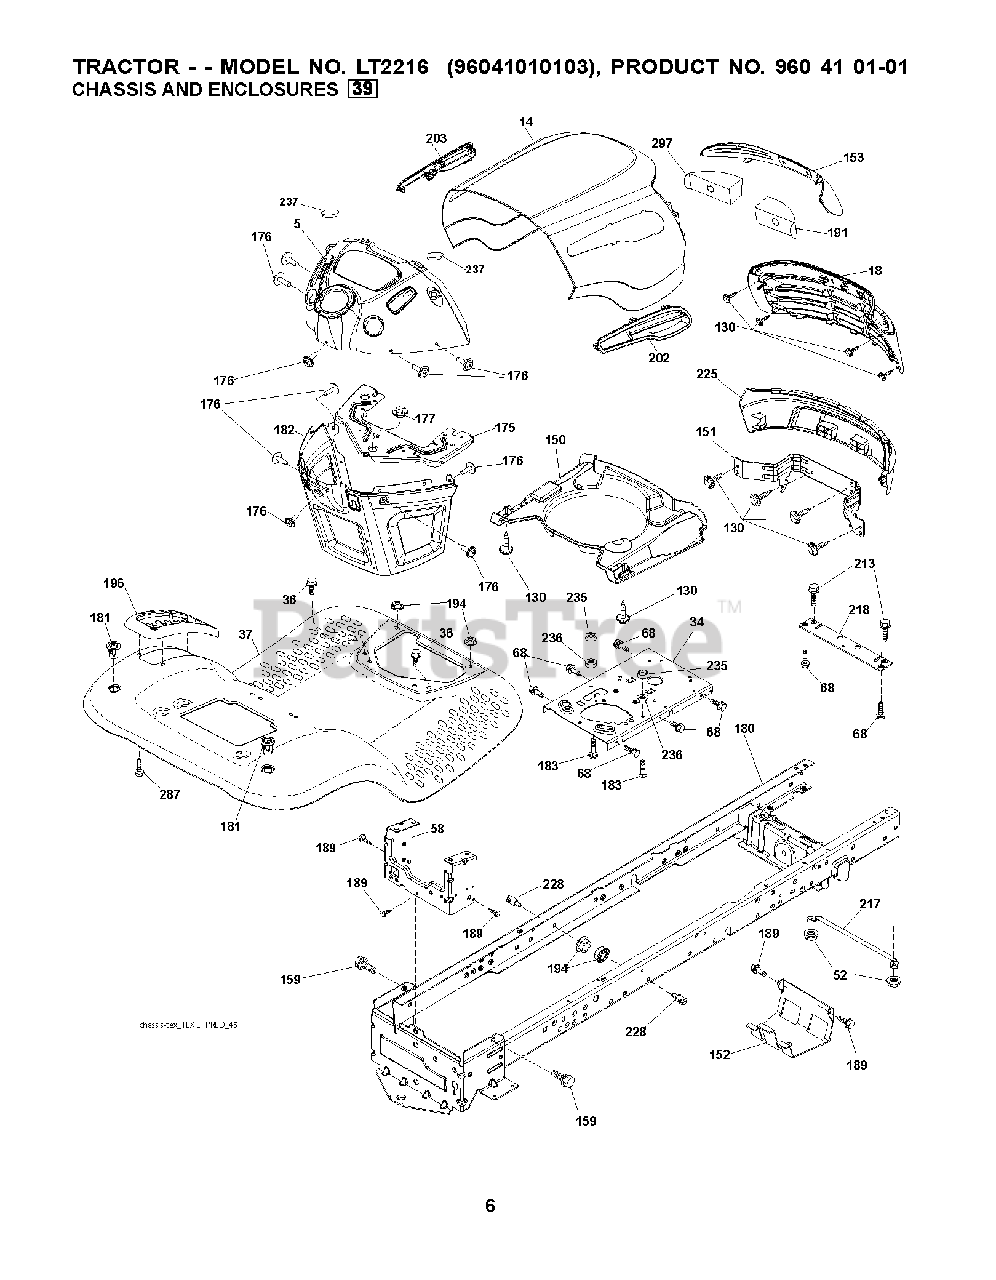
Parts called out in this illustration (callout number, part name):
34	PLATE.ENGINE.WELDED.CHASSIS
36	SCREW 5/16"
52	LOCKNUT
58	DRAWBAR UPPER 2PC SMALL FENDER
130	SCREW.#10 X 0.750.BOS THREAD
151	BRACKET.PIVOT.ALPHA.LT
152	SHIELD BROWNING
159	SCREW, 3/8-16X3/4
175	CROSSMEMBER
176	SCREW.#10-24X5/8.RN.QU
177	BUSHING STEERING
180	CHASS.WLDMNT.TL.12GA/2P.48/54
181	FEND/FTRST.PCH.CPH.NFW
182	DASH.LWER.PREDATOR/HUSQ.LT
183	BOLT.5/16-18X1-1/4 FULL THD
189	SCREW
191	INSERT.REFLECT.PREDATOR.LT.RH
194	NUT LOCK HEX FLANGE 5/16-18
196	CONSOLE.ASM.DECKLFT.BL/RBT.TLT
213	BOLT
217	ROD.PIVOT.HOOD
218	X-PIECE.HOOD.STOP.NON/
228	STUD.FASTNER.W/ANTI-ROTATE
235	SPACER FENDER
236	NUT.CENTERLOCK.5/16-
237	PLUG.MOUNT.CARGO.BLK
297	REFLECTOR.INSERT.PRED.LH.LT
